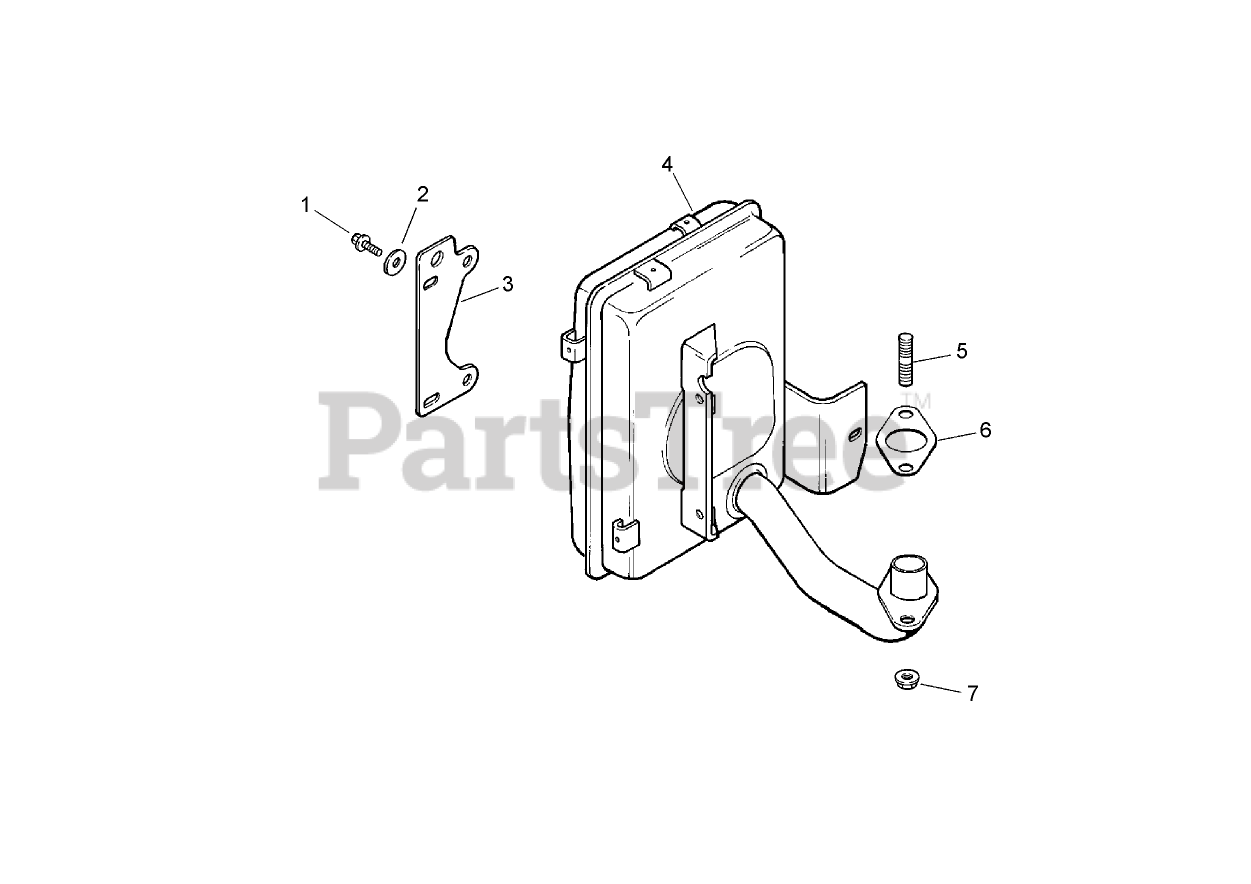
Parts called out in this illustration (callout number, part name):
1	SCREW-FLANGE, THREAD FORMING (M6X1.0X25)
2	Spacer
3	Bracket-Muffler
4	Muffler
5	STUD (M8X1.25X33)
6	Gasket-Manifold, Exhaust
7	NUT-FLANGE (M8X1.25)
